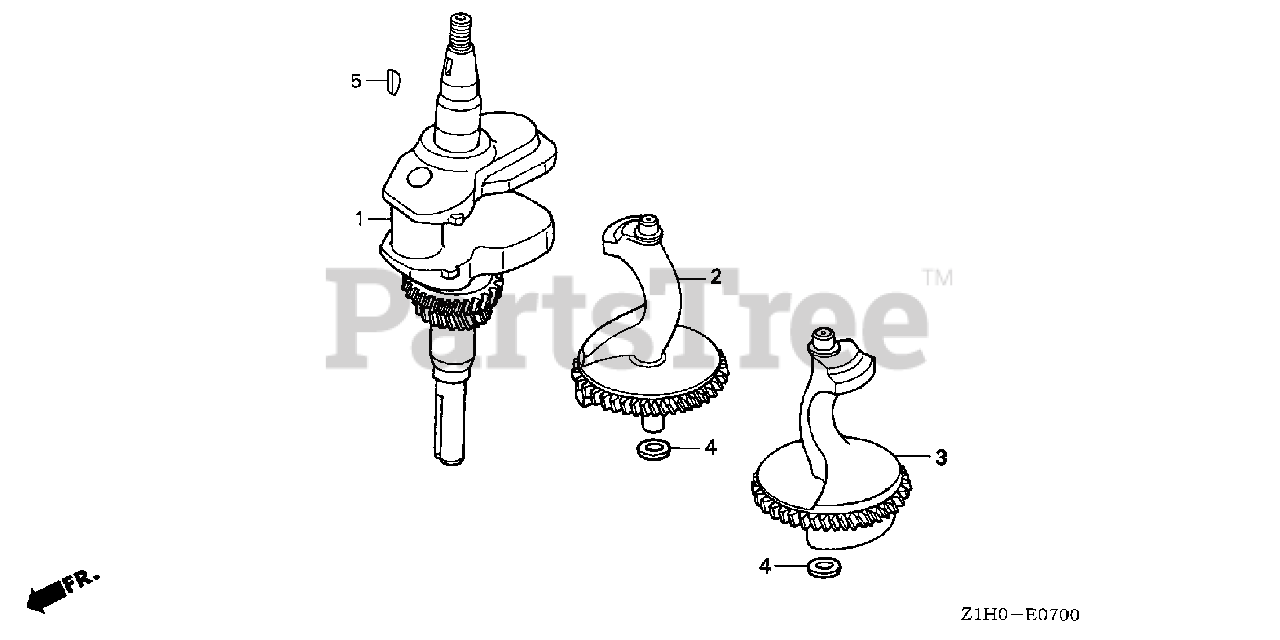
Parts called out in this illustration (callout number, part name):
1	CRANKSHAFT
2	WEIGHT A, BALANCER
3	WEIGHT B, BALANCER
4	WASHER, THRUST (15MM)
5	KEY, SPECIAL WOODRUFF (25X18)
